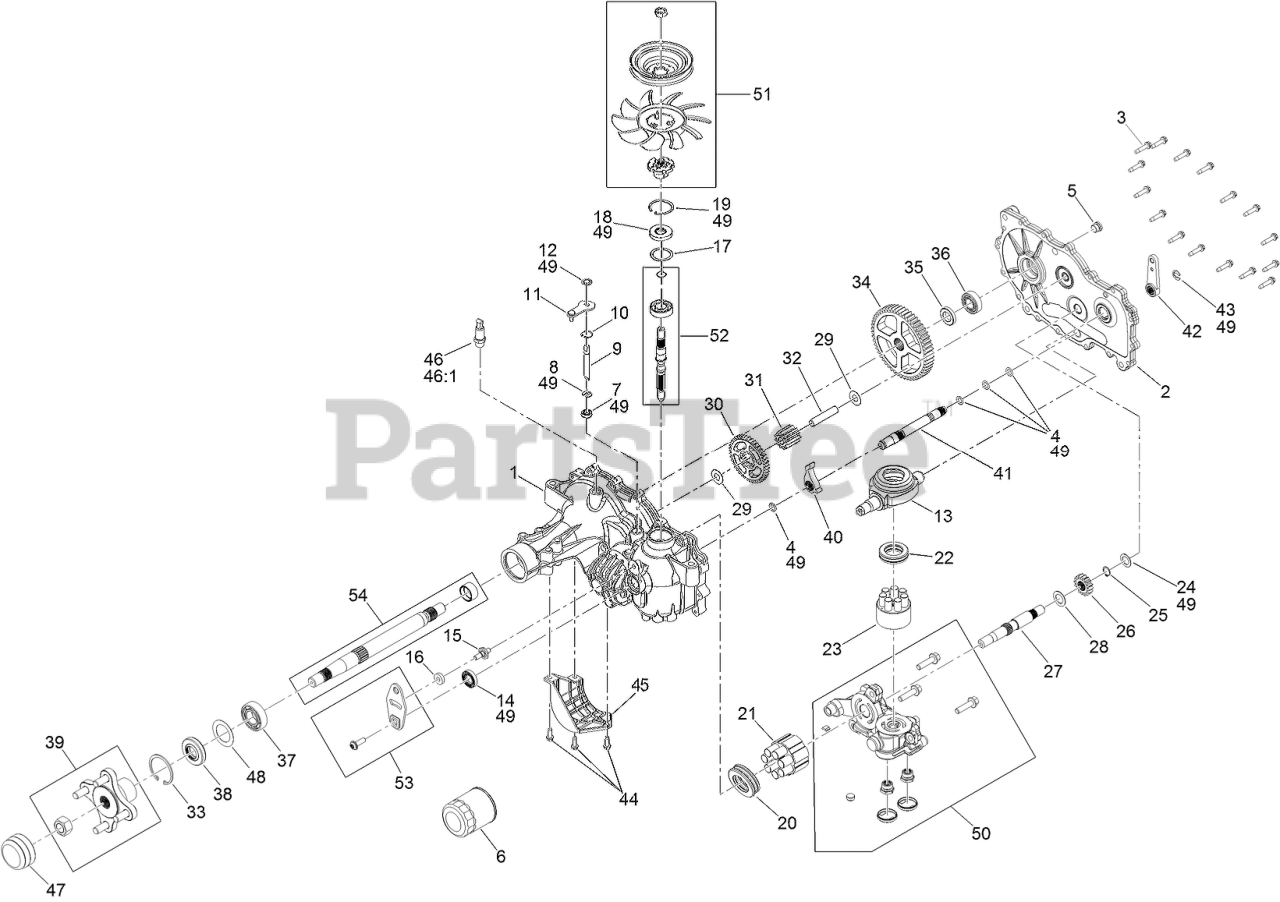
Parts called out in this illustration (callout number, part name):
1	MAIN HOUSING KIT
2	RH SIDE COVER KIT
3	SCREW-HHF
4	O-RING
5	PLUG-THREAD, STRAIGHT
6	ELEMENT-OIL FILTER, HYD
7	SEAL-LIP
8	RING-RETAINING, EXTERNAL
9	ROD-BYPASS
10	RING-RETAINING, INTERNAL
11	ARM-BYPASS
12	RING-RETAINING, EXTERNAL
13	SWASHPLATE-TRUNNION
14	SEAL-LIP
16	PUCK-FRICTION
17	SPACER
18	SEAL-LIP
19	RING-RETAINING
20	BEARING-THRUST
21	MOTOR CYLINDER BLOCK KIT
22	BEARING-THRUST
23	PUMP BLOCK ASM
24	WASHER-FLAT
25	RING-RETAINING
26	GEAR-16T
27	SHAFT-MOTOR
28	WASHER
29	WASHER
30	GEAR-43T
31	GEAR-11T
32	PIN-JACKSHAFT
33	RING-RETAINING
34	GEAR-54T
35	SPACER
36	BEARING-BALL
37	BEARING-BALL
39	HUB KIT
40	PAWL-BRAKE
41	SHAFT-BRAKE, INBOARD
42	HANDLE-BRAKE
43	RING-RETAINING, EXT
45	GUARD-FILTER, RH
46	ADAPTER-STRAIGHT
46:1	O-RING
47	COVER-NUT, AXLE
48	SPACER
49	SEAL KIT
50	RH CENTER SECTION KIT
51	FAN PULLEY KIT
52	INPUT SHAFT KIT
53	CONTROL ARM KIT
54	AXLE SHAFT KIT
